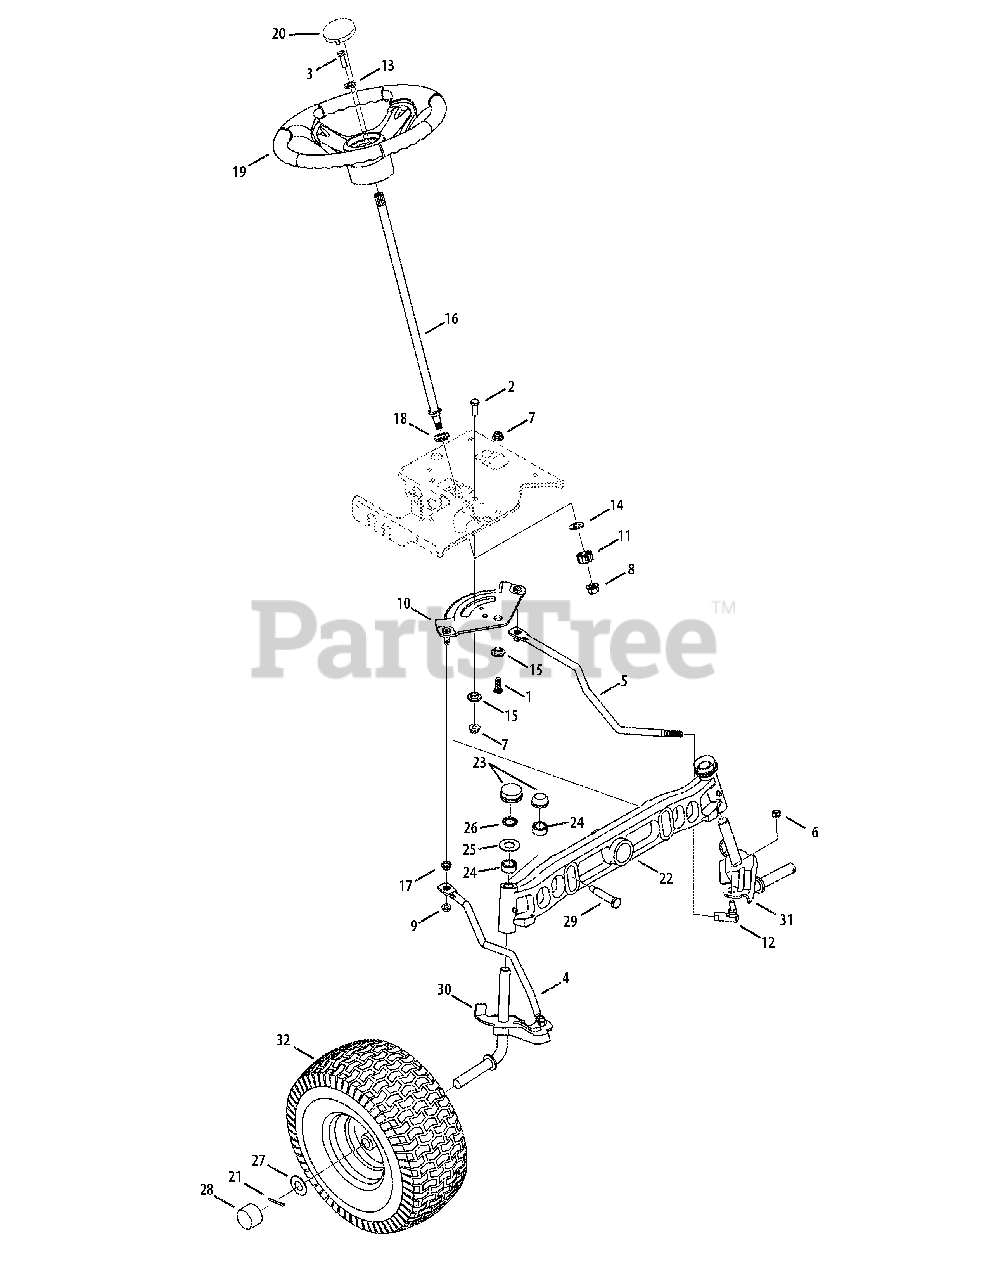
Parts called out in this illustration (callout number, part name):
1	Hex Screw, 3/8-16, 1.00, Gr5
2	Hex Screw, 3/8-16, 1.00, Gr5
3	Hex Screw, 5/16-18, 1.00, Gr5
4	Link, Drag, RH
5	Link, Drag, LH
6	Nut, Hex Lock, 3/8-24
7	Nut, Flange Lock, 3/8-16
8	Nut, Flange Lock, 7/16-20
9	Nut, Flange Lock, 5/16-18, Gr5
10	Gear, Steering, 11/90 Ratio
11	Gear, Pinion, Steering
12	Ball Joint, 7/16-20, Lock
13	Washer, Flat,.406 x .875 x .105
14	Washer, Flat,.51 x 1.12 x.06
15	Spacer, Shoulder,.38 x 1.00 x .31
16	Shaft, Steering, .625 OD x 24.25
17	Plastic Bushing.380 ID
18	Hex Flange Bearing 5/8 PM
19	Steering Wheel, 13.25 Soft Grip
19	Steering Wheel, 13.25
20	Steering Wheel Cover, No Logo
20	Steering Wheel Cover, w/ Logo
21	Cotter Pin, 5/32 x 1.25
22	Pivot Bar Axle
23	Large Cap
23	Small Cap
24	Spacer, .71 x .125 x .56
25	Washer, Flat, .78 x 1.59 x .060
26	Push Nut, 3/4 dia.
27	Flat Washer, .781 x 1.589
28	Hub Cap
29	Shoulder Bolt, .500 x 2.38, 3/8-16
30	Axle Assembly
31	Axle Assembly
32	Wheel Assembly
32	Tire Only 16 x 6.50 x 8 Sq. Shldr.
